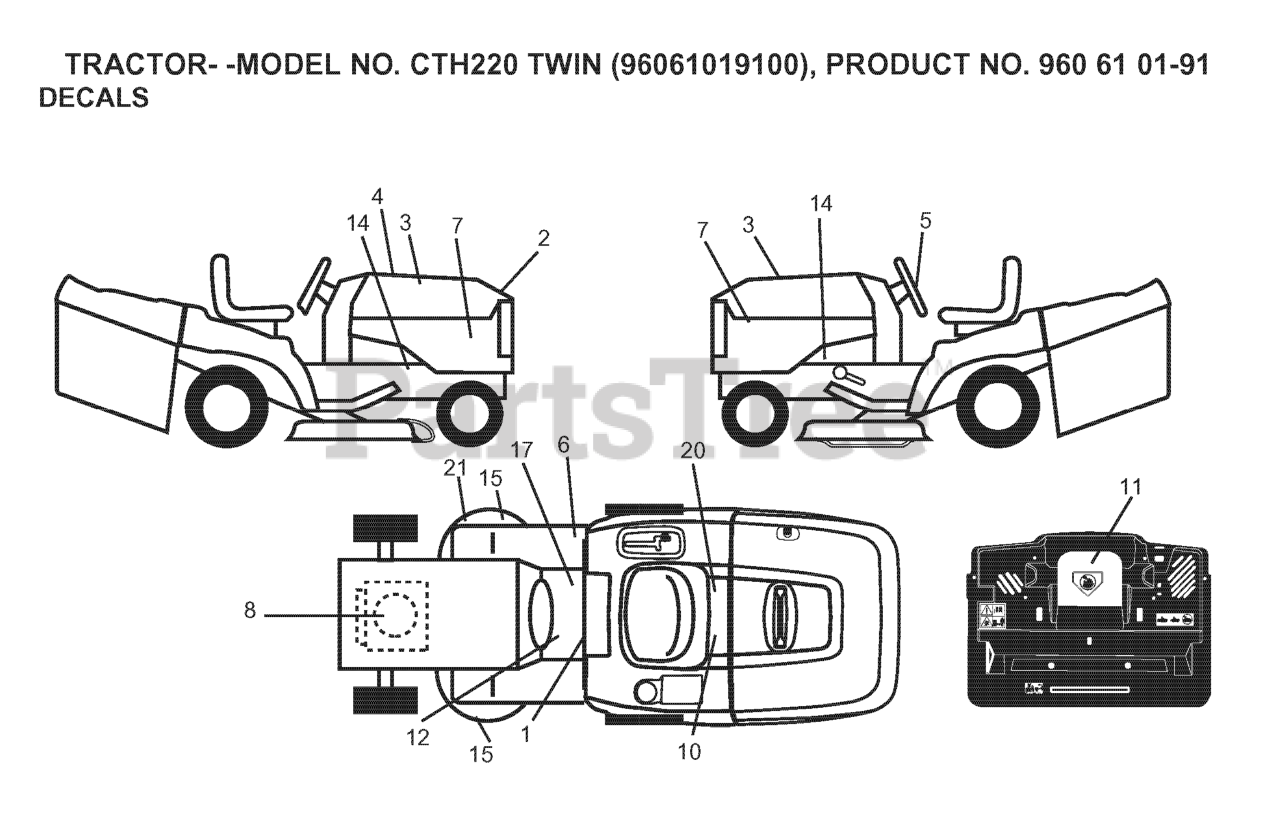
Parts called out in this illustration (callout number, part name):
1	LABEL
2	DECAL.HOOD.TOP.INSERT.
3	DECAL.HOOD.NAMELOGO.HUSQ
5	DECAL.WHEEL.STRG.LGN.H
6	Decal, Fender 100 DB/CE
8	DECAL
10	DECAL BTRY SYMBOLS
11	DECAL.INTERNATIONL.CUTFINGER
12	DECAL
17	DECAL PARK BRAKE
20	DECAL.BYPASS.FENDER.CRD.LT.YT
